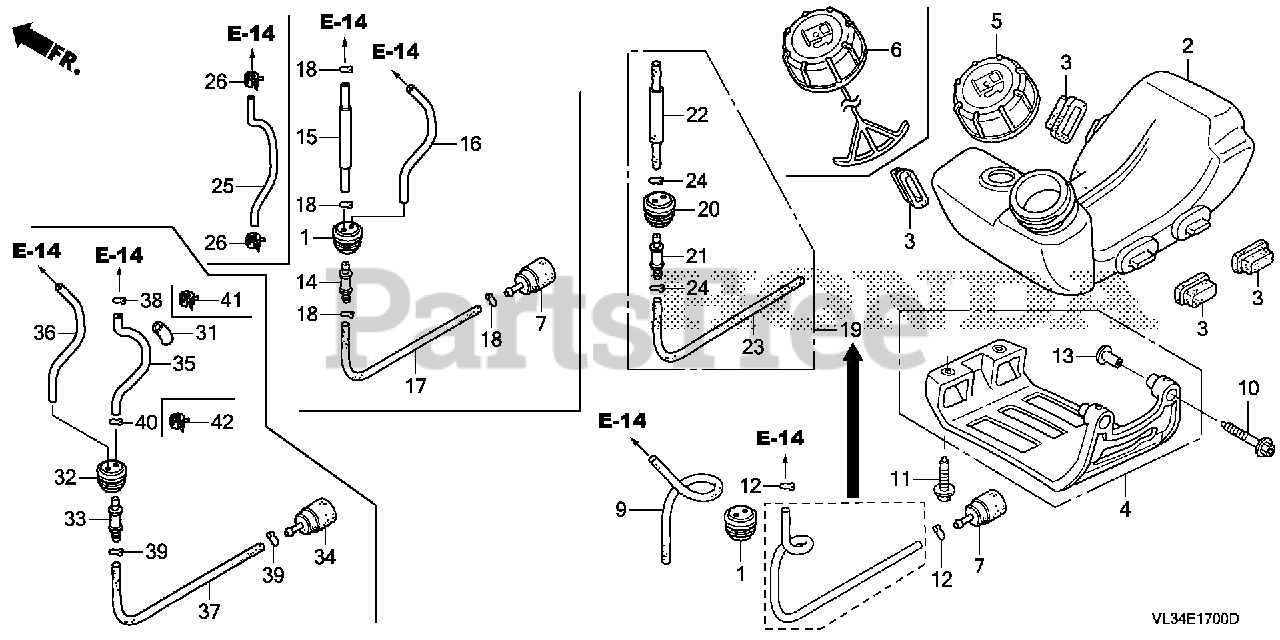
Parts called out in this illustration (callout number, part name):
2	TANK, FUEL
3	RUBBER, TANK MOUNTING
4	GUARD, TANK
5	CAP ASSY., FUEL TANK
6	CAP ASSY., FUEL TANK
10	BOLT, SOCKET (5X30)
11	BOLT, SOCKET (5X16)
13	COLLAR, TANK GUARD
31	PROTECTOR, TUBE
32	GROMMET, FUEL TUBE
33	JOINT, FUEL TANK
34	FILTER, FUEL
35	TUBE, FUEL (FKM)
36	TUBE, FUEL RETURN
37	TUBE A, FUEL
39	CLIP, TUBE (B1 5)
41	CLAMP, TUBE (D5.5)
42	CLAMP, TUBE (D5.5)
